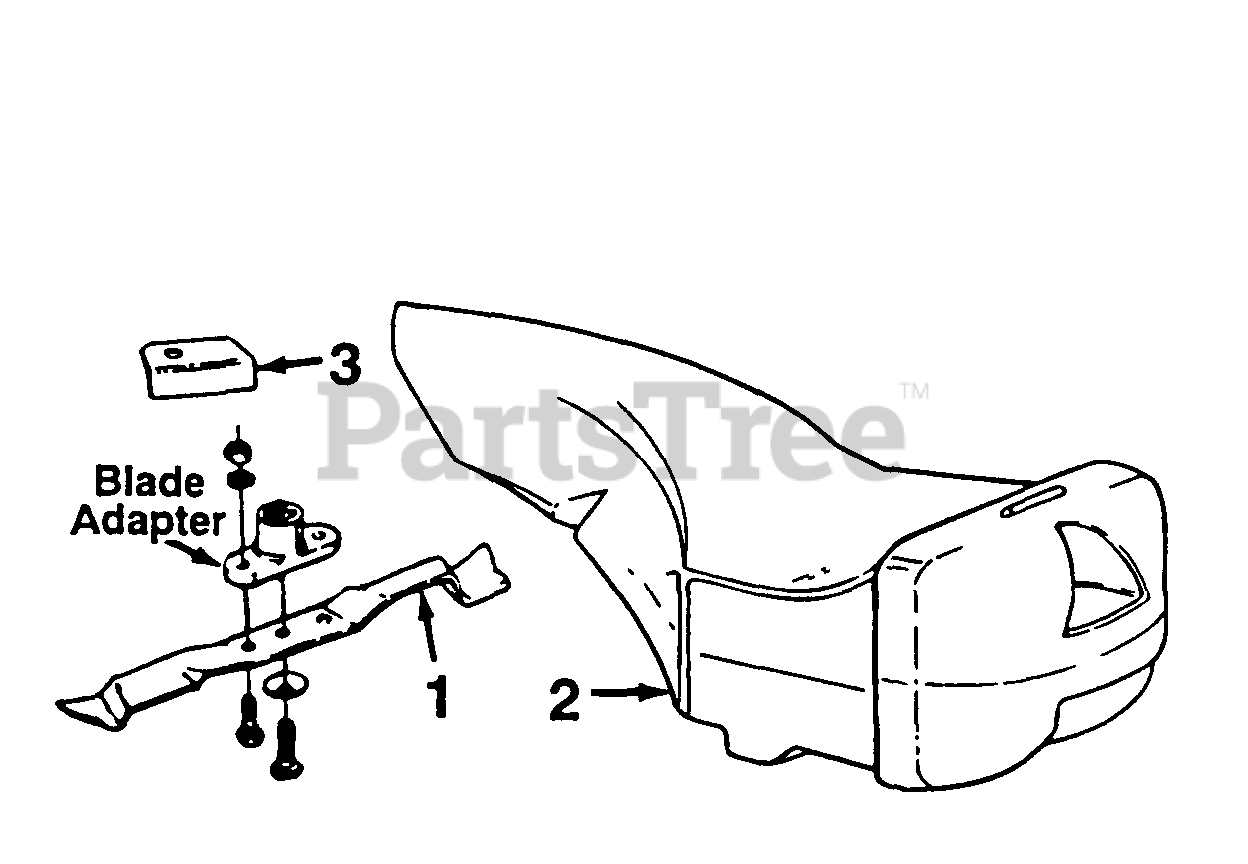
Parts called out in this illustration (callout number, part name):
1	Mulching Blade
2	Mulching Plug
3	Stop Bracket
